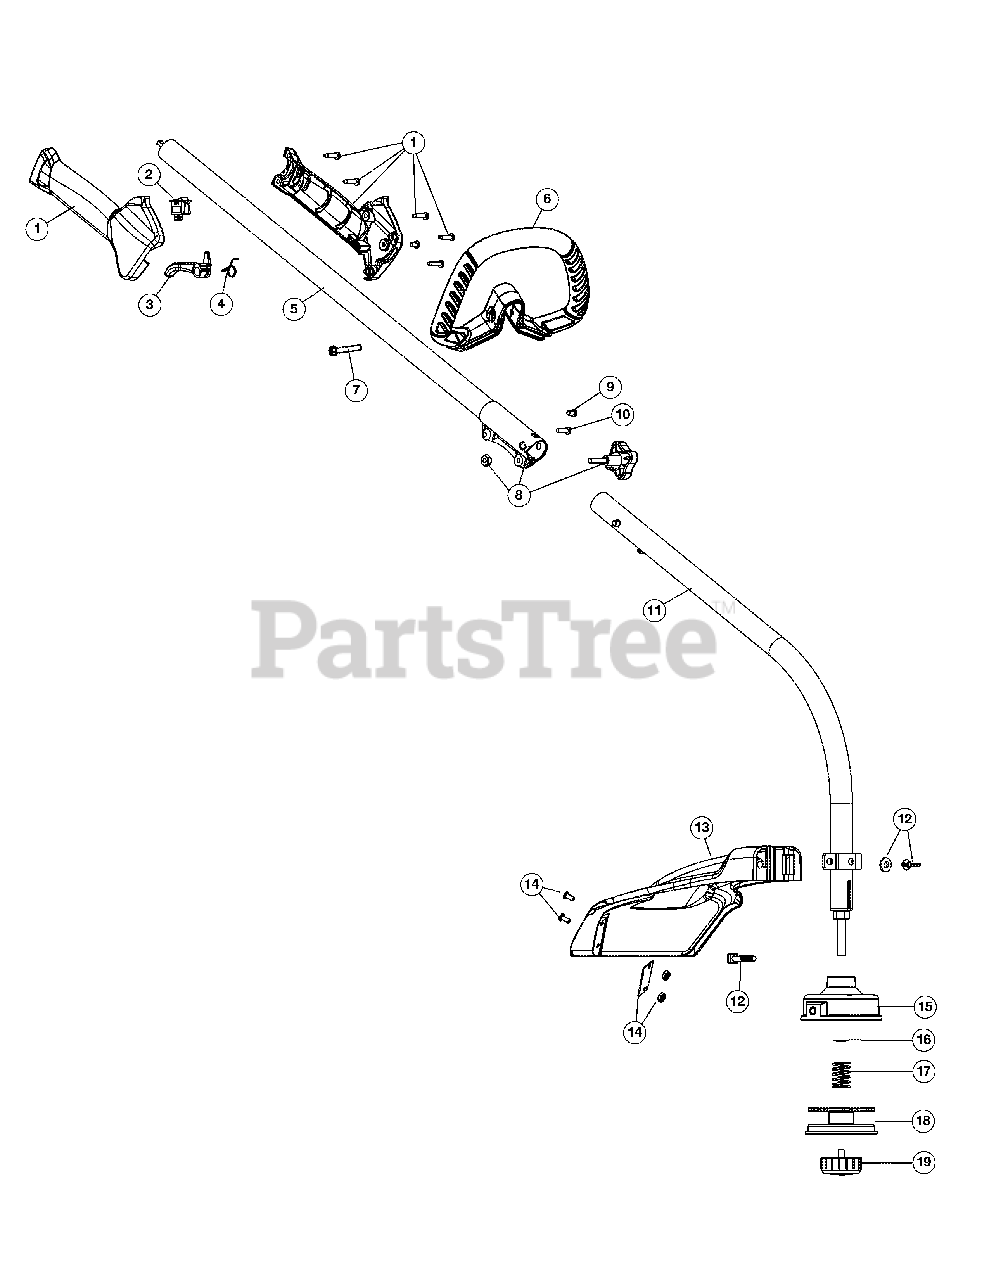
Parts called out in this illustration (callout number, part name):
1	Throttle Housing Assembly (Incl. 2-4)
3	Throttle Trigger
4	Throttle Trigger Spring
5	Upper Shaft Housing Assembly
6	D-Handle (Incl. 7)
7	D-Handle Hardware Assembly
8	Split Boom Coupler (Incl. 9-10)
9	Anti-Rotation Screw
11	Lower Shaft Housing Assembly
12	Shield Mounting Hardware
13	Shield Assembly (Incl. 14)
14	Blade Assembly
15	Outer Spool Assembly (Incl. 16)
18	Inner Reel
19	Bump Head Knob Assembly
